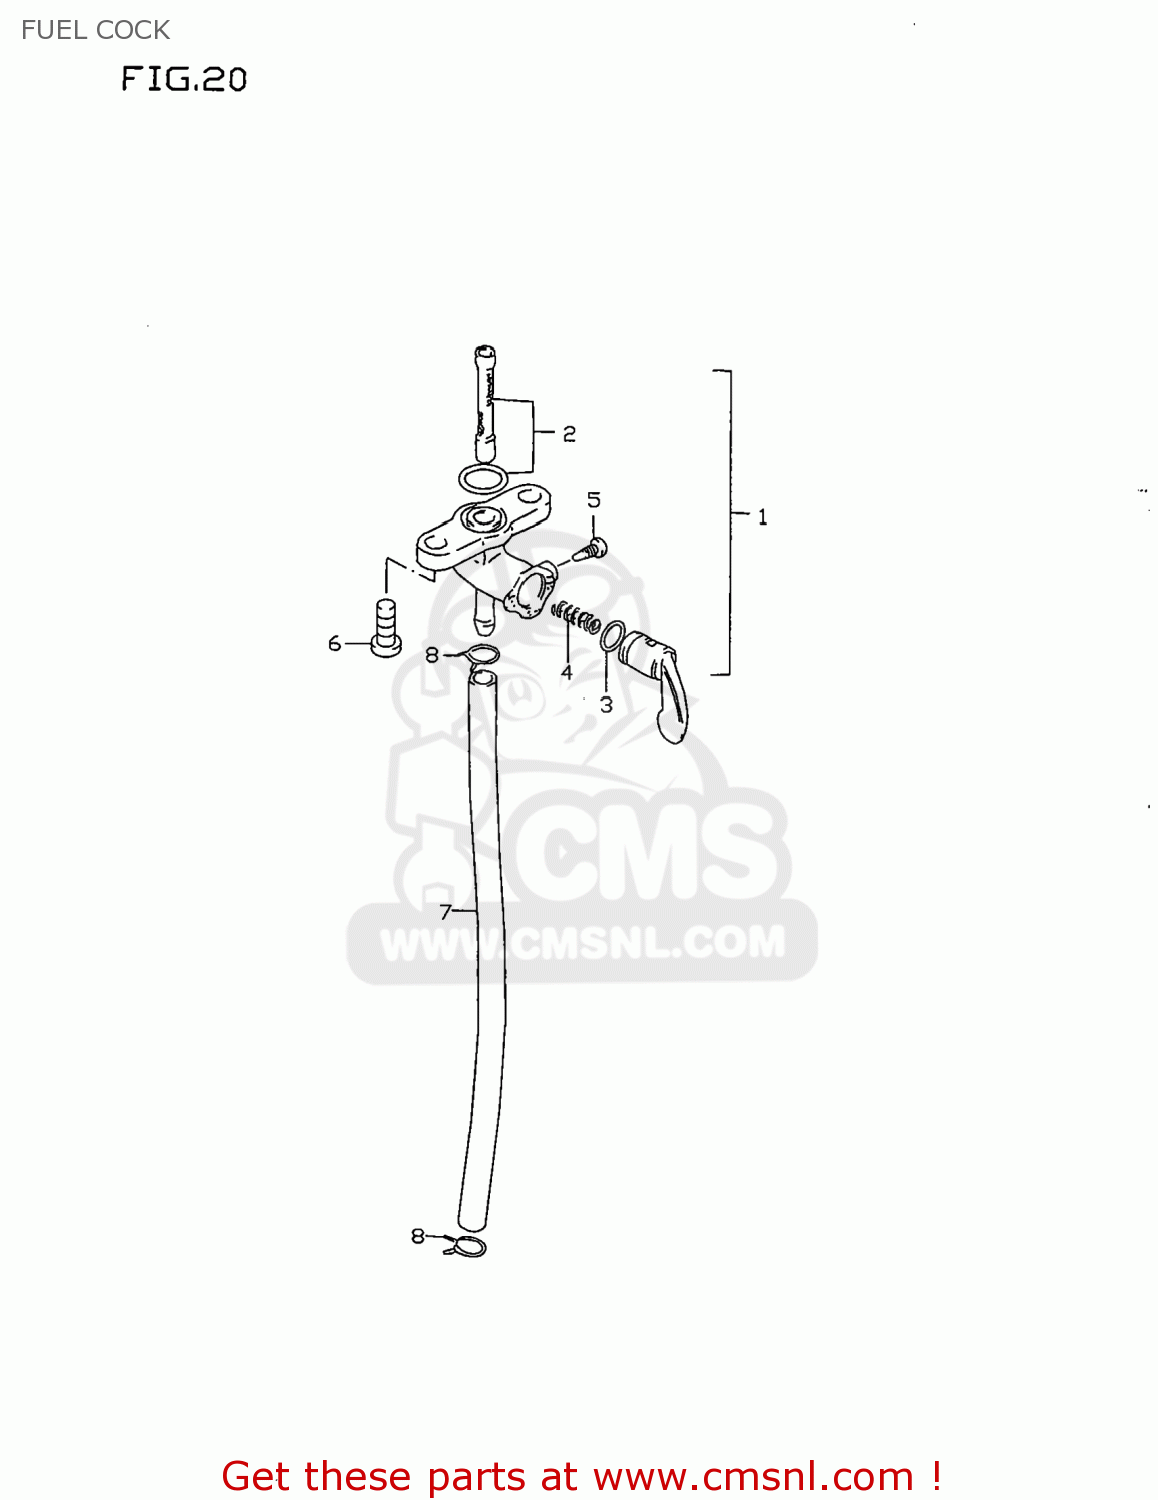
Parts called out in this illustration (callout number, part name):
1	COCK ASSY,FUEL
2	FILTER SET FUEL
3	O RING,LEVER
4	SPRING
5	SCREW
6	SCREW
7	HOSE(5X8.2X600)
8	CLIP
